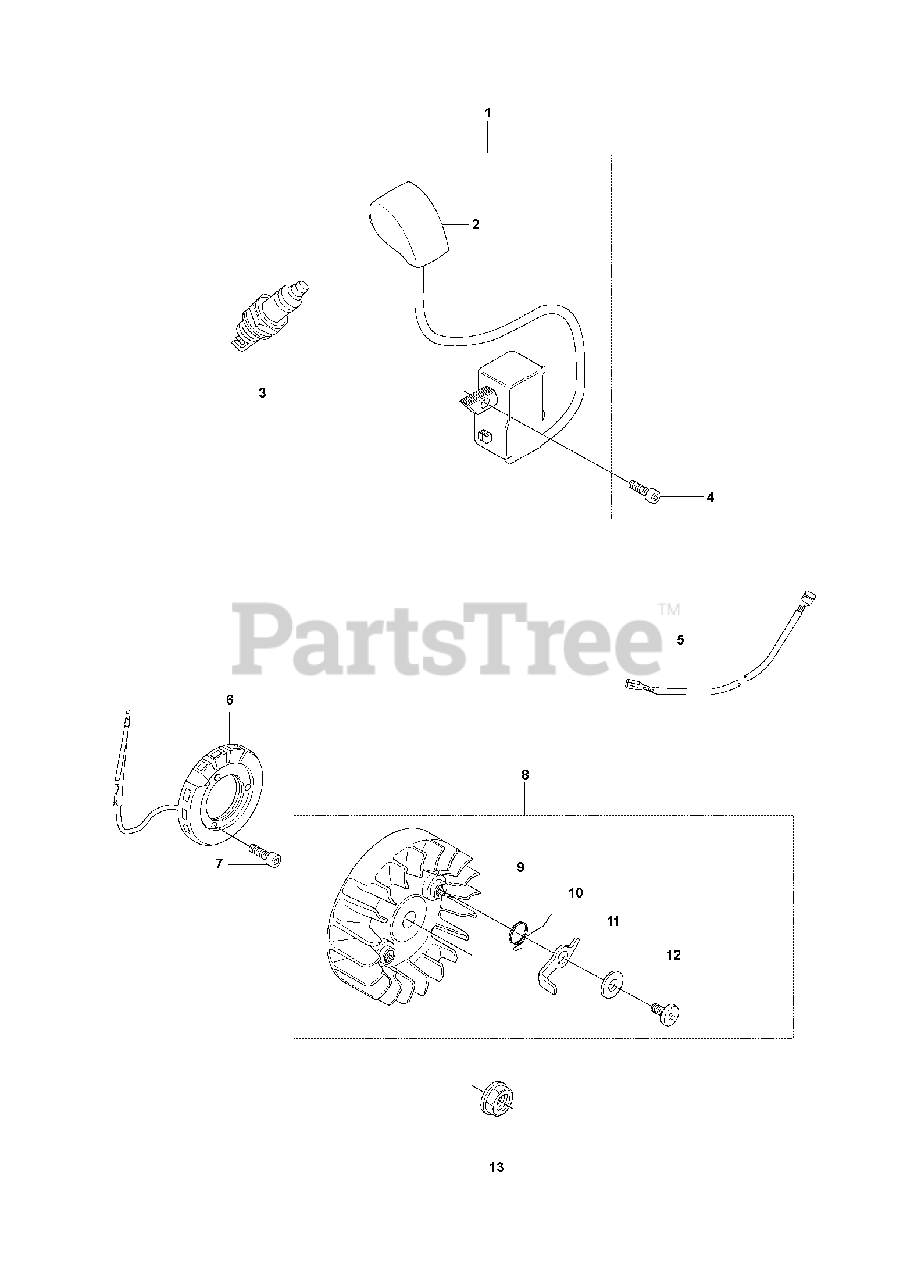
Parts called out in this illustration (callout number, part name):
1	IGNITION MODULE
2	SPARK PLUG CONNECTOR
3	SPARK PLUG RCJ6Y NLA
5	SHORTING LEAD
6	GENERATOR
9	SPRING
10	STARTER PAWL
11	WASHER
12	PIN, STARTER CATCH
13	NUT W/ WASHER
